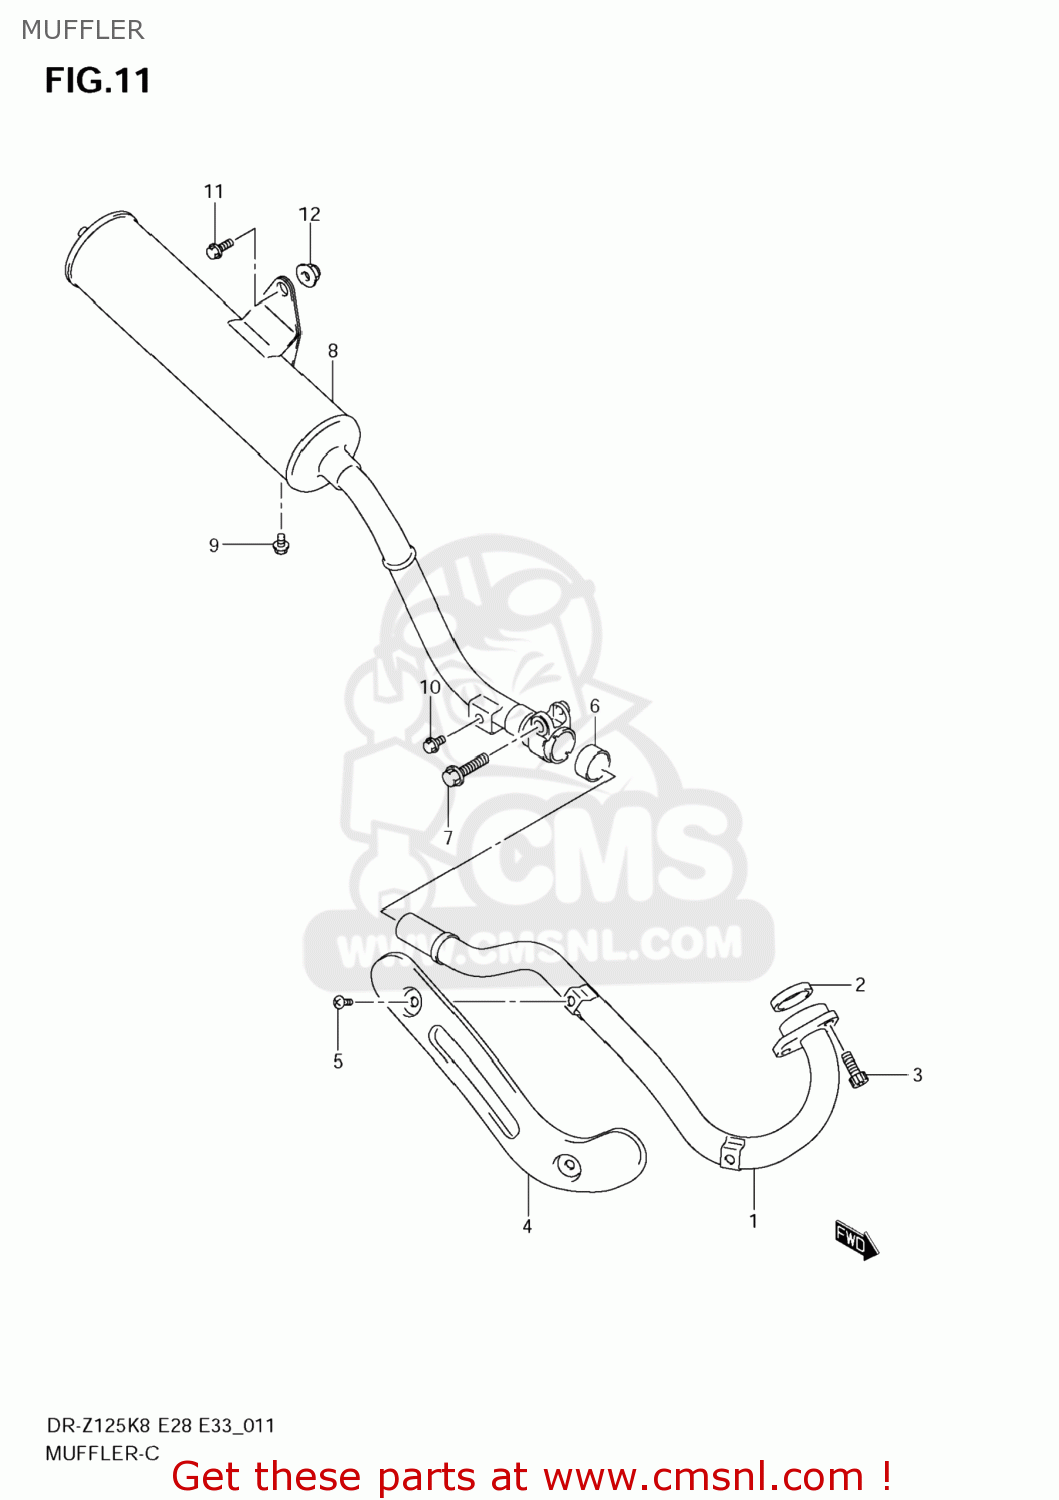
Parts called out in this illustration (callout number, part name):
1	PIPE,EXHAUST
2	GASKET (NAS)
3	BOLT
4	COVER,EXHAUST PIPE
5	SCREW(6X10)
6	CONNECTOR,MUFFLER
7	BOLT
8	BODY,MUFFLER
9	BOLT
10	BOLT
11	BOLT(8X23)
12	NUT
